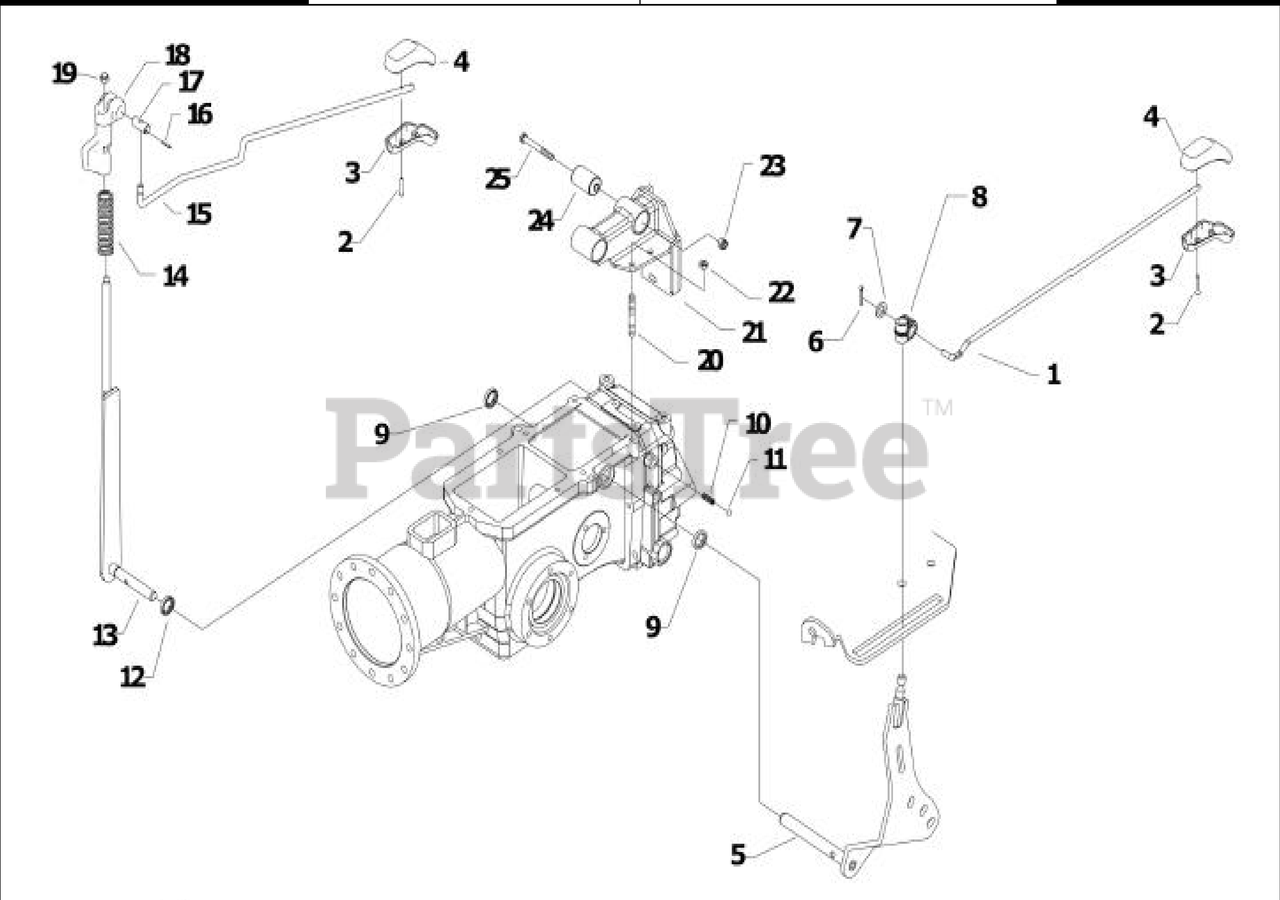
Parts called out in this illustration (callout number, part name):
1	HI / LO RANGE CONTROL ROD
2	SCREW 3,5X25
5	LEVER HI / LO RANGE
6	SPLIT PIN A3X15 UNI 1336
7	WASHER 10,5x18
8	JOINT HI / LO RANGE
9	OIL SEAL 14X22X4
12	OIL SEAL AS15X26X7 DIN 3760 NBR
13	LEVER PTO
14	SPRING
15	PTO CONTROL ROD
17	HINGE
18	JOINT PTO
19	SELFLOCK NUT M8
20	STUD BOLT M10X46X24X16
21	SUPPORT BRACKET
23	SELF LOCK NUT M12
24	SILENT BLOCK 12X40X58X66
25	SCREW TE M12X100 UNI 5737
